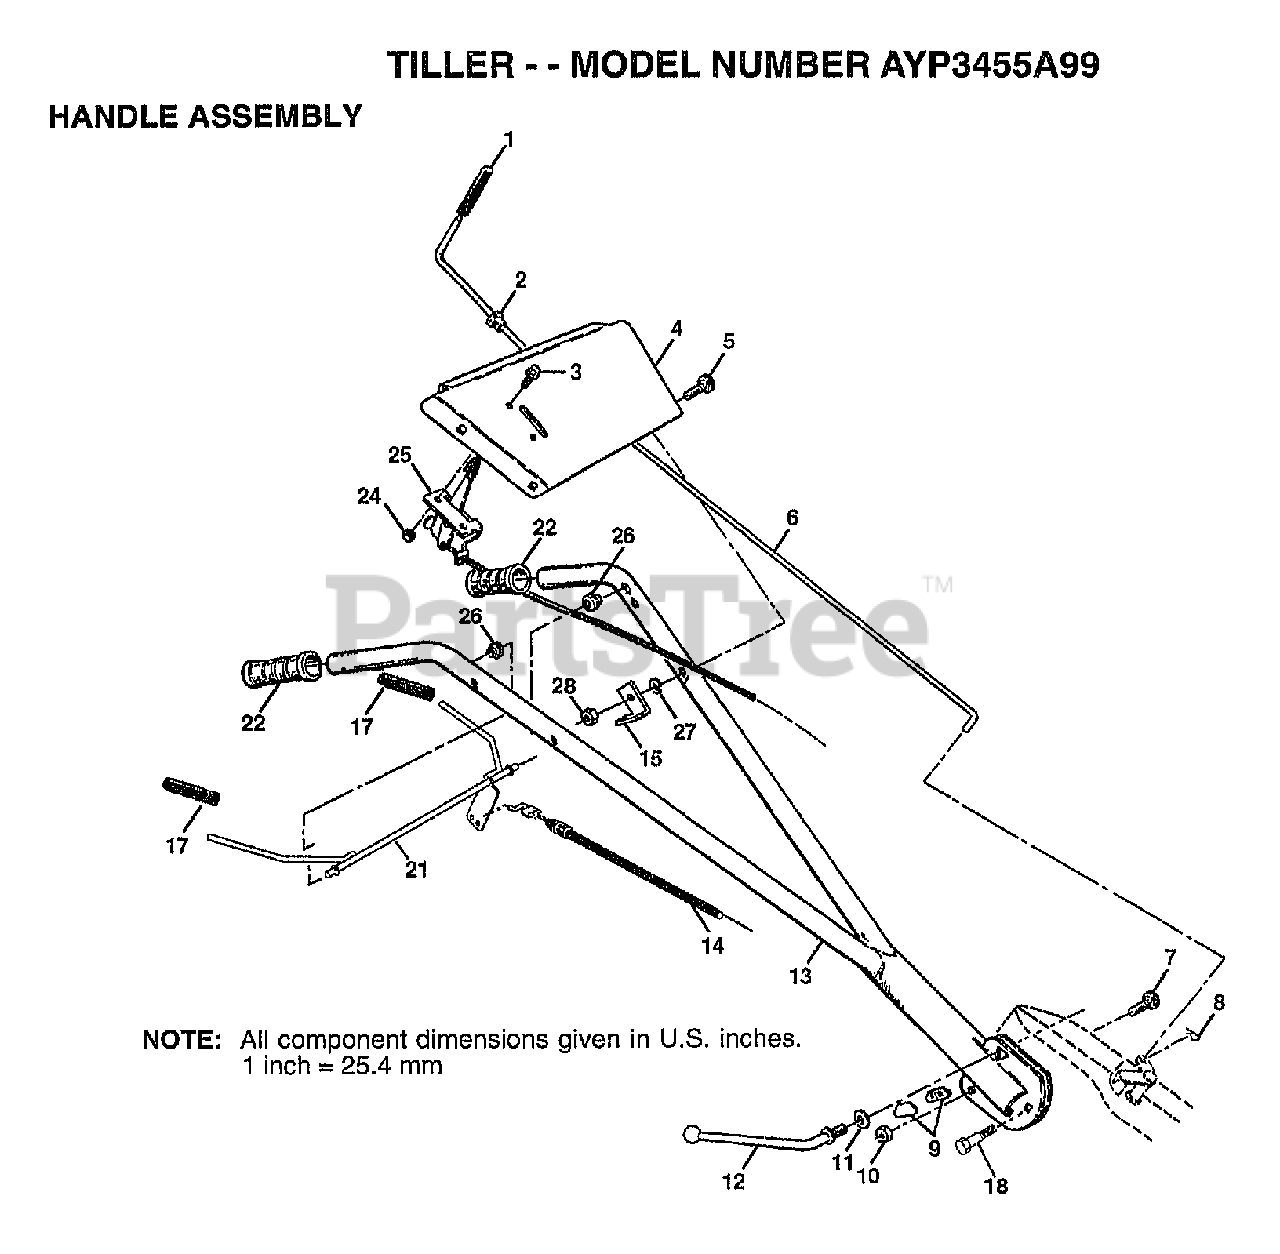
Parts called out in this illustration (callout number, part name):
1	GRIP TI
2	BUSHING
3	SCREW.PNHD.10-24
4	HANDLE BRACKET
5	BOLT CARRIAGE CRT
6	ROD SHIFT CRT
7	BOLT D
8	RETAINER M
9	LOCK CRT
10	LOCKNUT
11	WASHER CRT
12	LEVER LOCK CRT
14	"CABLE, CLUTCH"
15	BRACKET.CLUTCH.CA
17	GRIP BAR CRT
18	BOLT PIVOT
21	BAR CONTROL
22	"GRIP,HANDLE"
25	"CONT,THROTTLE"
26	GROMMET.HANDLE.V-
27	LOCKWASHER
28	NUT
